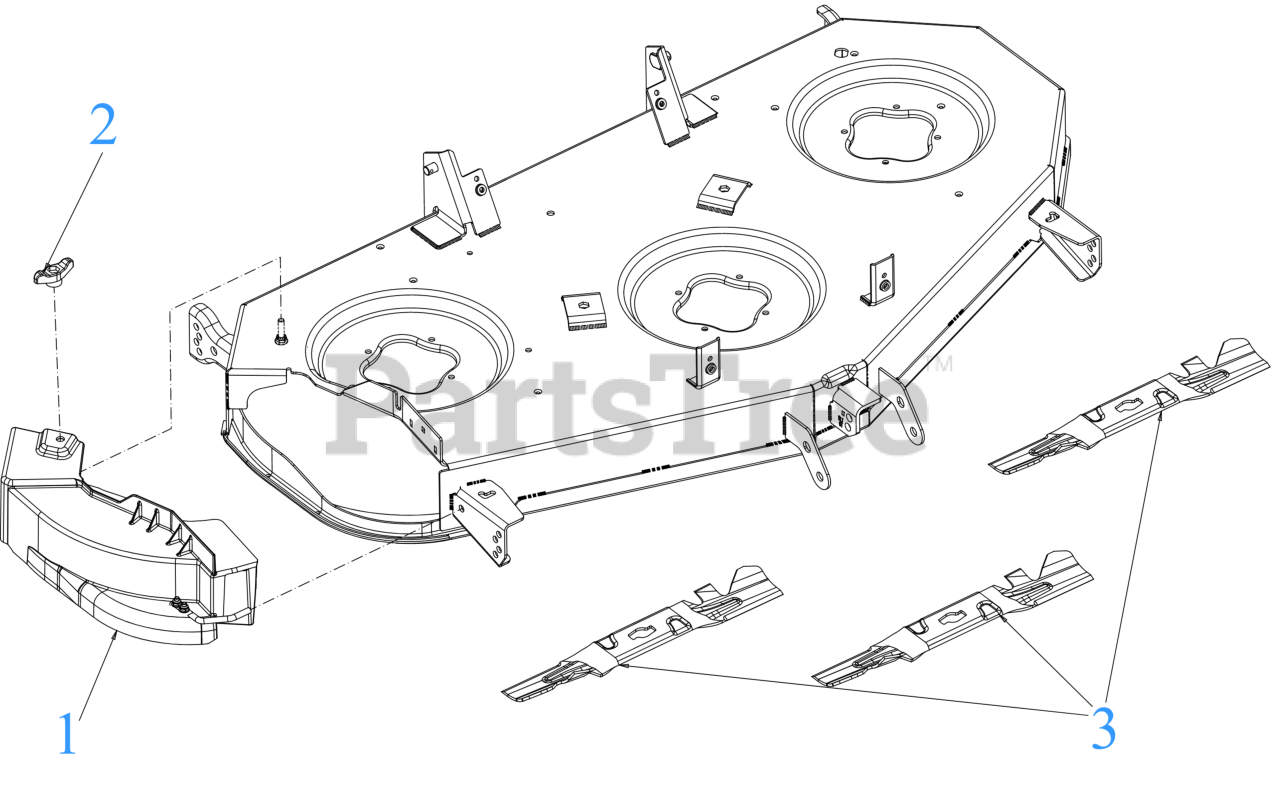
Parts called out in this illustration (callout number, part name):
1	MULCH PLUG
1	FLANGE LOCK NUT
1	MULCH PLUG MOUTING ROD
1	SCREW 1/4-20X.75 GR5
1	FLAT WASHER
2	WING KNOB 5/16-18
3	17.271" XTREME BLADE (2IN1) (S SHAPE CENTER HOLE)
